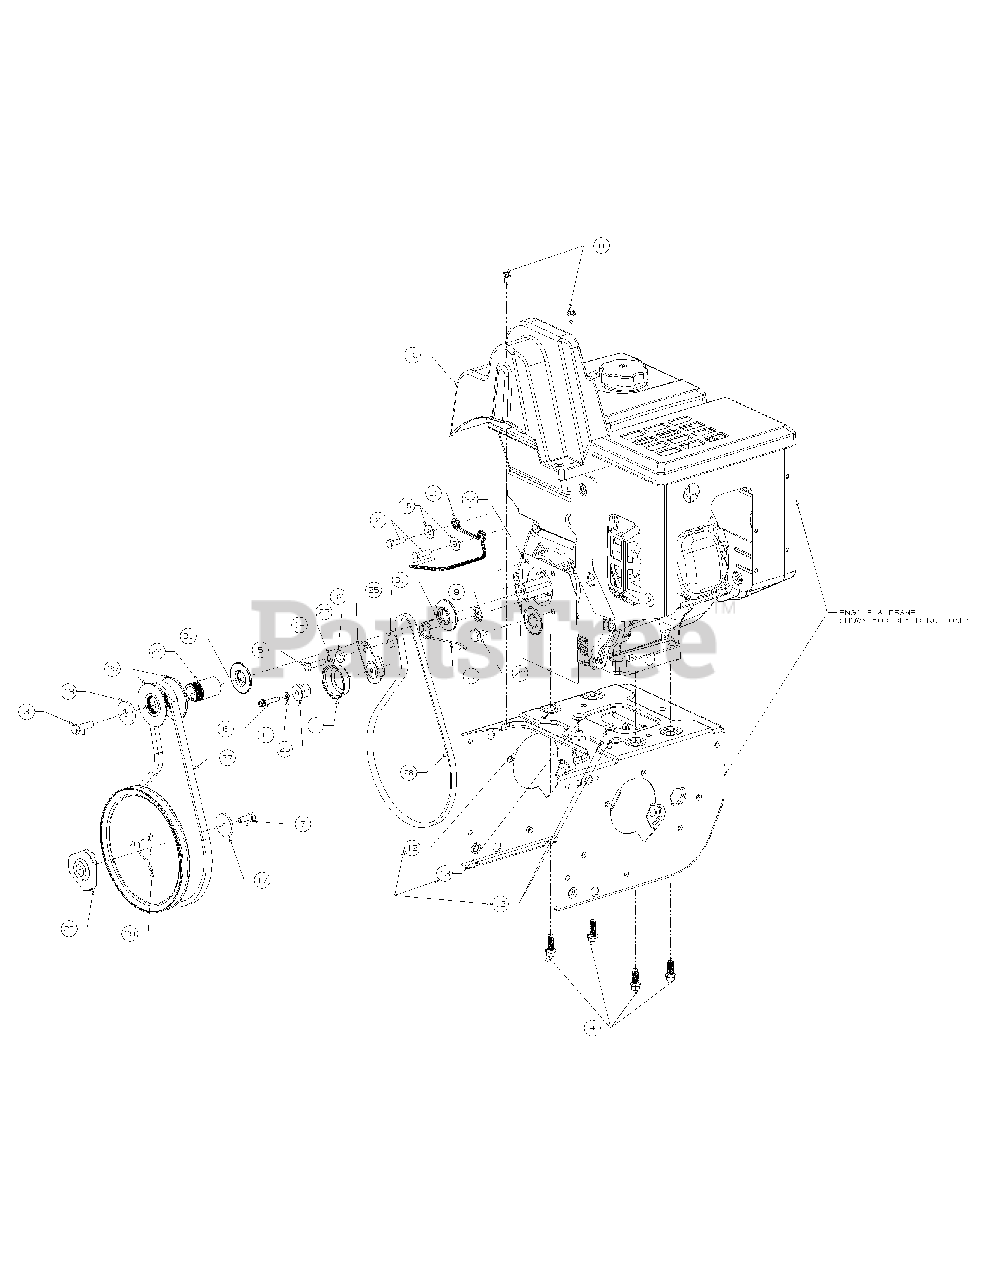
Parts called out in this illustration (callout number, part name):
1	Pulley Asm:Idler
2	Hhcs-5/16-24 X 1.0
3	Screw 3/8-24X1.25
4	Screw-Hex
5	Screw-Hex 5/16-24
6	Screw-Hex 1/4-20 X
7	Screw-Hex Cap 5/1
8	Screw Hex.Wash.Hd
9	Nut-Push On
10	Cover-Belt 4 Way
11	Spring-Torsion
12	Plug-3/8 Dia Id X
13	Plug-1/2 Id X 3/32
14	Washer-Lock 5/16
15	Washer-Fl
16	Washer-Lock
17	Washer-Fl
18	Washer-Flat
19	Grease
20	Screw-Shoulder
21	Guide-Belt
22	Pulley-Adapter .75
23	Spacer-Shoulder
24	Spacer-Pulley
25	Spacer-Idler Brkt
26	Spacer:Shoulder
27	Belt-.500 X 37
28	Belt-V Type 3/
29	Pulley-Auger 8.1 O
30	Pulley-Half 4L V
31	Pulley Half-3/8 V
32	Bracket-Idler Drive
33	Plate-Cove
